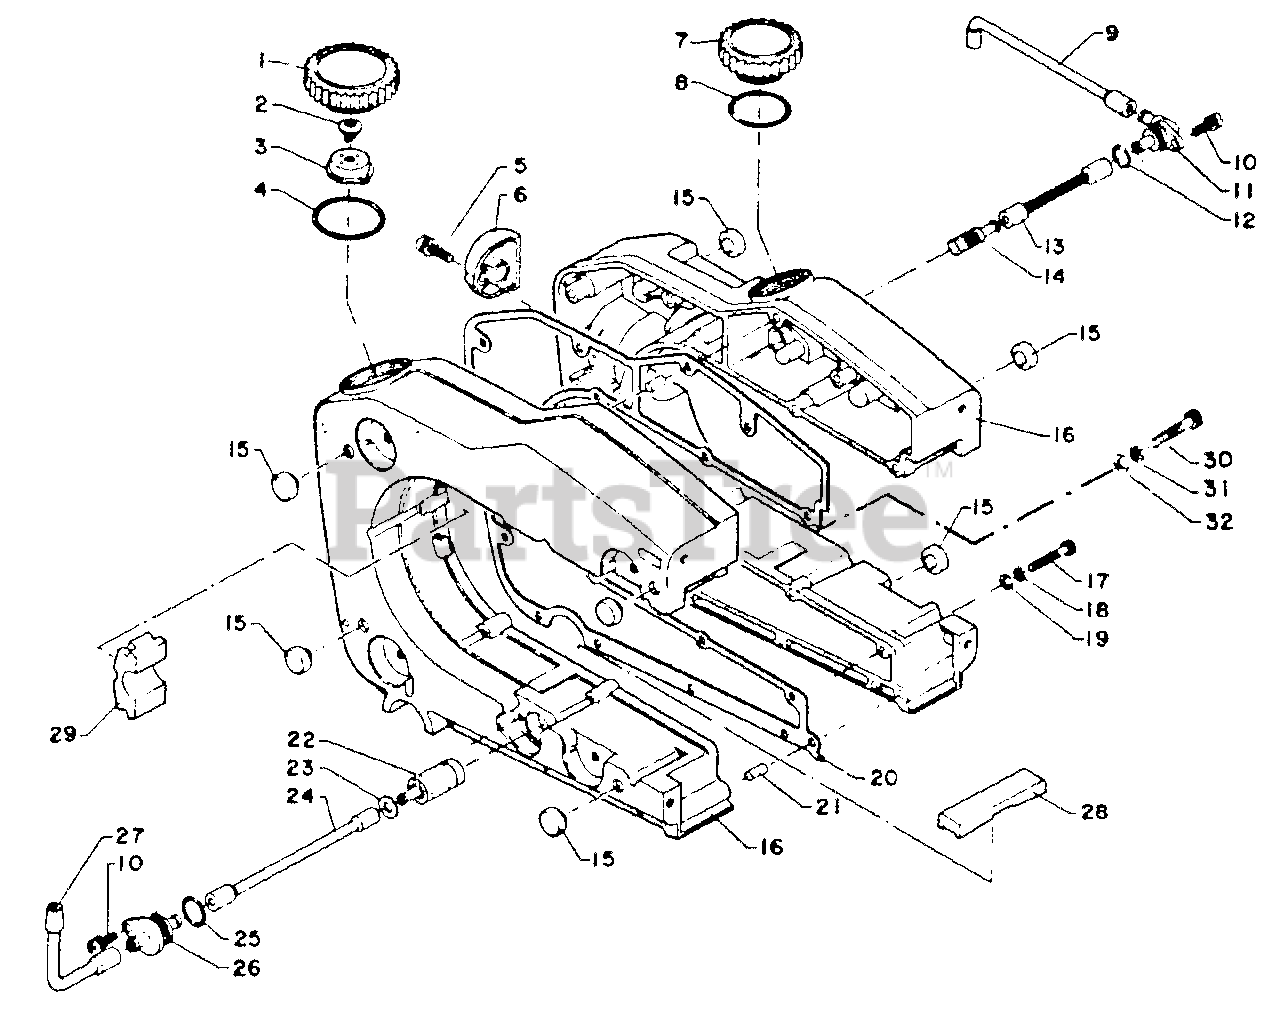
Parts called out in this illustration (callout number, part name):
1	CAP ASSY
2	VALVE, CHECK
3	HOLDER, VENT
4	O-RING 29
5	SCREW 5×15
6	OIL PUMP COVER
7	CAP, OIL TANK
8	O-RING 25 MM
9	PIPE, OIL - OUTER
10	SCREW 4×12
11	CONNECTOR, PIPE
12	O-RING 9 MM
13	PIPE - INNER
14	FILTER, OIL
15	STOPPER (A)
16	TANK, FUEL
17	SCREW - 4×20
18	WASHER, SPRING 4 MM
19	WASHER 4 MM
20	GASKET, FUEL TANK
21	PIN, LOCATING 5×10
22	FILTER, FUEL
23	WASHER 6.5×11.5×0.8
24	PIPE - INNER
25	O-RING 12 MM
26	CONNECTOR, PIPE
27	PIPE, FUEL - OUTER
28	STOPPER (B)
29	STOPPER (C)
30	SCREW - 5×25
31	LOCKWASHER - 5
32	WASHER
